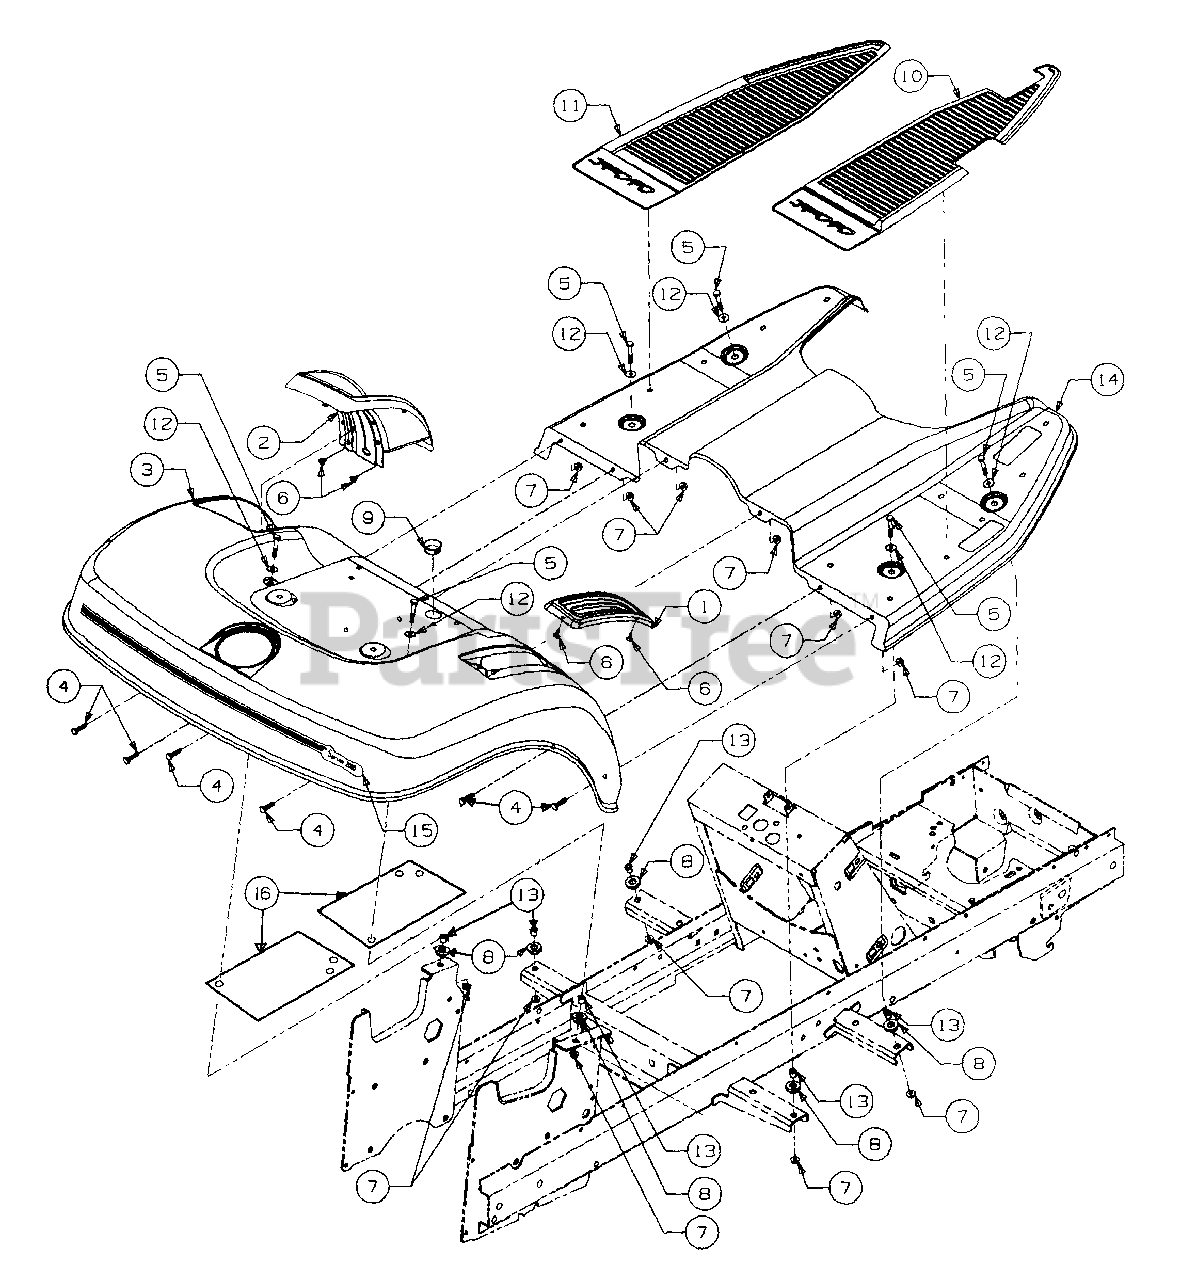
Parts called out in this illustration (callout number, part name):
1	Cover, 6-Speed Shifter
2	Cover, Implement Lift
4	Screw, Hex Cap, 1/4-20 x .62 GR5
5	Screw, Hex Cap, 1/4-20 x 1.0
6	Screw, Hex Tapp, #10 x .38 Lg
7	Nut, Hex Flange Lock, 1/4-20
8	Grommet, Insolater
9	Bushing, Snap, 7/8 ID
10	Pad, RH Foot
11	Pad, LH Foot
12	Washer, Flat, .255 x .72 x .06
13	Spacer, .28 ID x .40 OD x .42 Lg
14	Running Board w/Graphic
15	Graphic, Rear Fender
